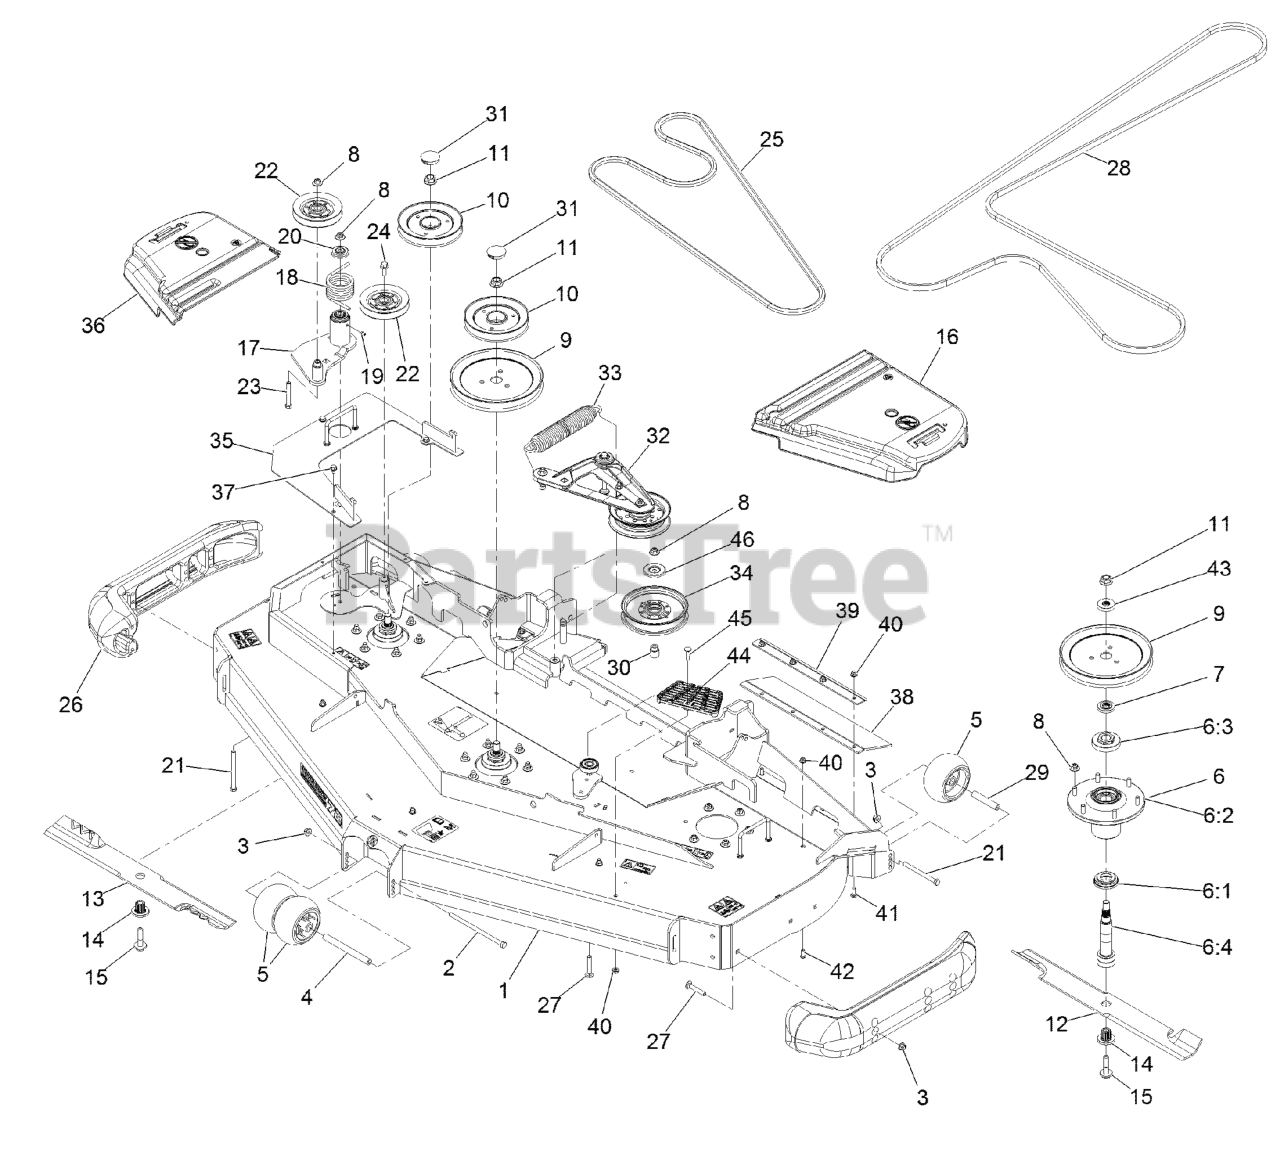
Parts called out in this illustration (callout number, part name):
1	DECK-RD72 NLZ, W/DECALS
2	SCREW-HH
3	NUT-HF, NI
4	SPACER-WHEEL
5	ROLLER-SCALP, ANTI
6	ASM,SPINDLE HOUSING
6:1	GUARD,BOTTOM
6:2	ASM,CUTTER HOUSING
6:3	NUT, SPINDLE 7/8-14
6:4	SPINDLE,DOUBLE SPLINE
7	SPACER,SPLINED STEPPED
8	Nut-Nyloc 3/8-16 Flg
9	SHEAVE,BLADE DRIVE 9.00
10	SHEAVE-RD, REVERSE DRIVE
11	NUT-FLANGE, CENTERLOCK
14	BUSHING,SPLINED
15	SCREW,SEMS 1/2-20 X 2.19
16	COVER-BELT, LH
17	IDLER ASM
18	SPRING-TORSION
19	FITTING-GREASE
20	GUARD-TOP
21	SCREW-HH
23	SCREW-HH
24	SCREW-HHF
26	SKID-BUMPER, DECK
27	Bolt-Carriage 3/8-16 X 2 1/4
28	BELT
29	TUBE-SPANNER
30	BUSHING-IDLER
31	PLUG,BLACK NYLON 1.75
32	DECK IDLER ASM
33	SPRING-EXTENSION
34	IDLER-PULLEY, FLAT 6.00X1.00
35	COVER-REVERSE DRIVE
36	COVER-BELT, RH
38	GUARD-TIRE
39	SUPPORT-OUTER FLAP
40	NUT-HF, NI
41	SCREW-CARR
42	SCREW-HSBH
43	SPACER,SPLINED
44	STEP-DECK
45	Bolt-Carriage 5/16-18 X 1 1/4
46	SHIELD-DUST
